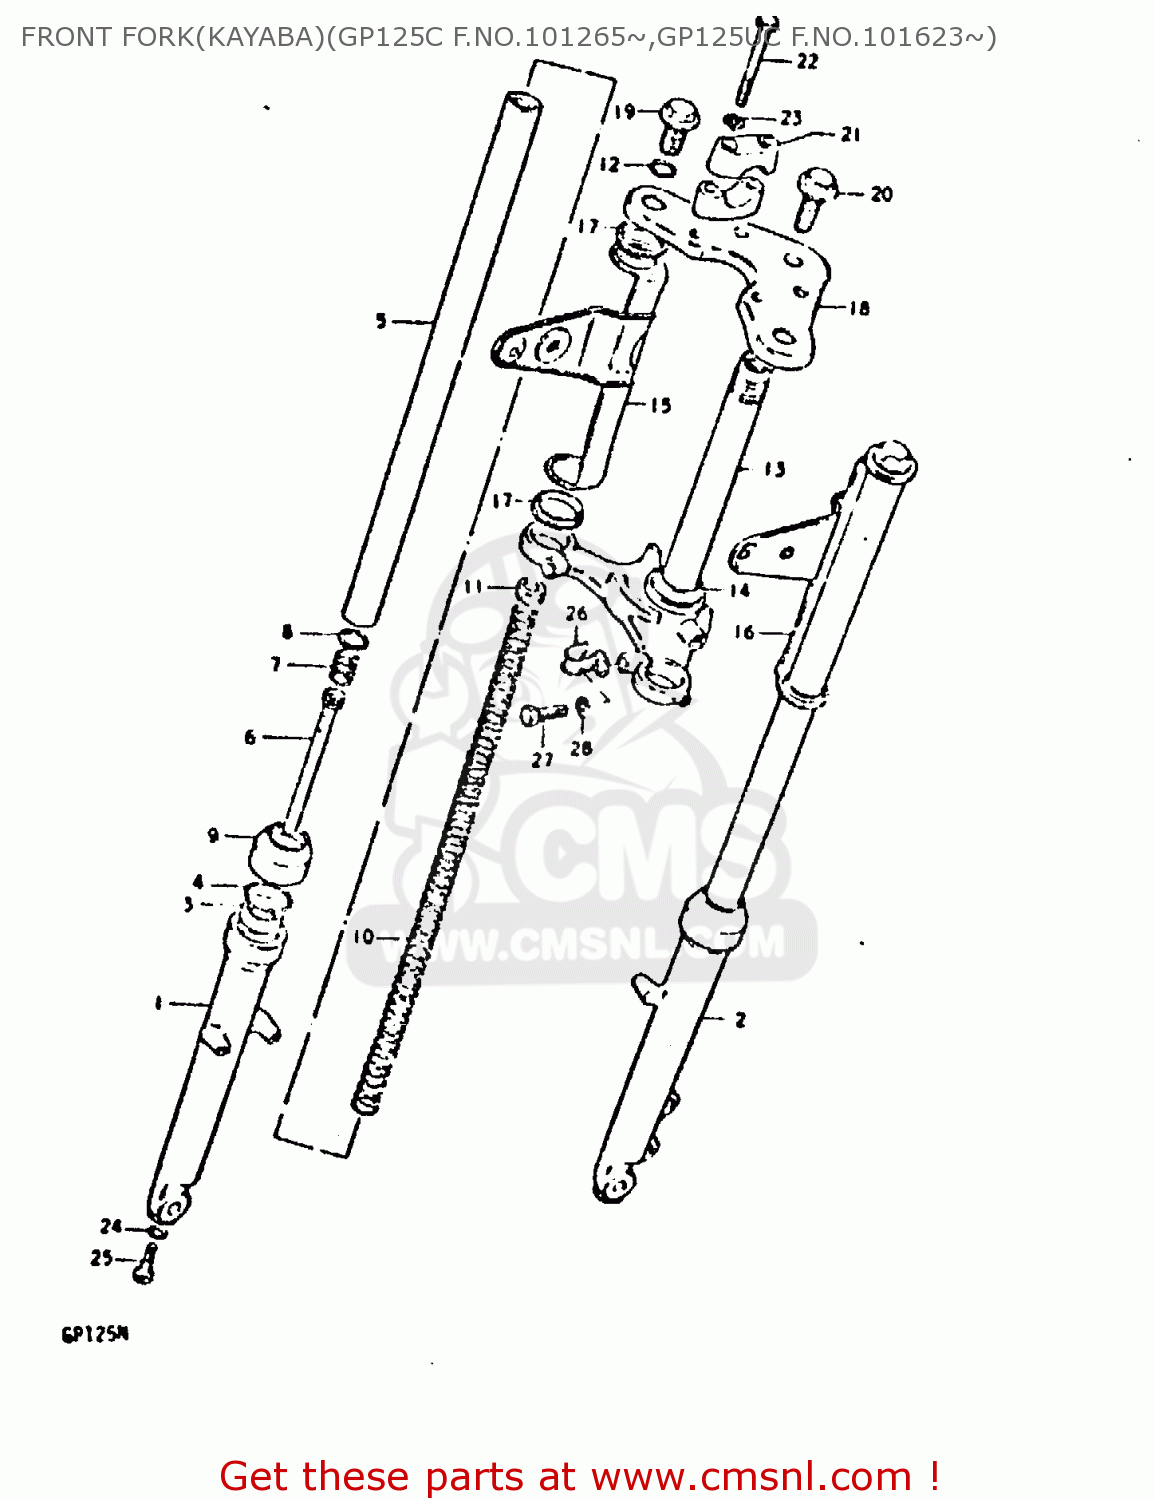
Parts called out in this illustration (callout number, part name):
1	OUTER TUBE, RH
2	OUTER TUBE, LH
3	SEAL,OIL
4	RING,SNAP
5	TUBE, INNER
6	CYLINDER
7	SPRING
8	RING
9	DUST SEAL
10	SPRING
11	NUT
12	O-RING,FORK INNER TUBE
13	STEM, STEERING
14	RACE,STEERING OUTER LWR
15	BRACKET, HEADLAMP RH (BLACK)
16	BRACKET, HEADLAMP LH (BLACK)
17	GASKET (NAS)
18	HEAD, STEERING STEM (BLACK)
19	CAP
20	BOLT
21	HOLDER,HANDLE UPR
22	BOLT 8X55
23	LOCK WASHER
24	GASKET (NAS)
25	BOLT,FORK CYLINDER(10X25)
26	CLIP,SPEEDOMETER CABLE
27	BOLT 10X30
28	LOCK WASHER
